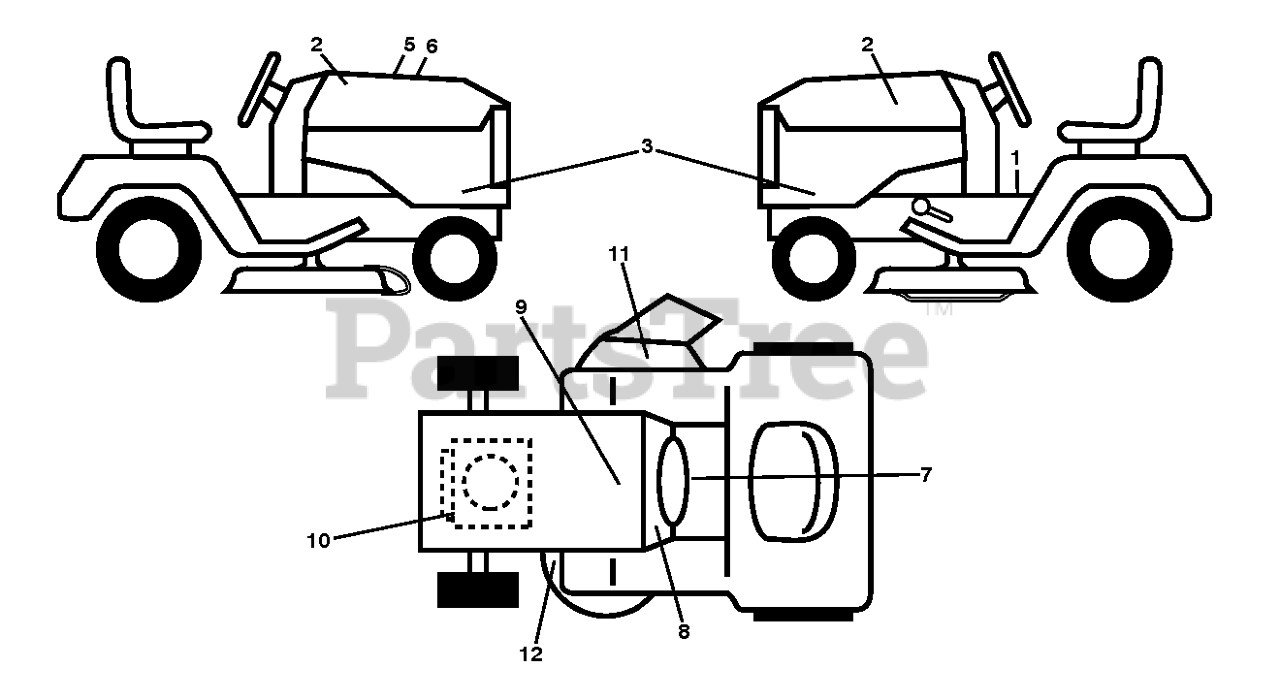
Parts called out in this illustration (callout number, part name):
1	DECAL.WARNING.2007.ENG/FR
2	DECAL.BADGE.170MM.TEXTLOGO.
3	DECAL.SDPNL.GT2.YTH20V46.SET
4	DECAL.MOWER.WARN.KEEP.HAND.AWY
5	DECAL.WARNING.CUST.RESP.E85.
7	DCL.WARNING.SPARK.IGNITION.CA
8	DECAL.SNOWFLAKE.MS498.HUSQ
9	DECAL BTRY SYMBOLS
10	DECAL DECAL.ENG.BS.ENDUR.20HP.
12	DECAL.V-BELT.SCH.42/46"MEC/ELE
